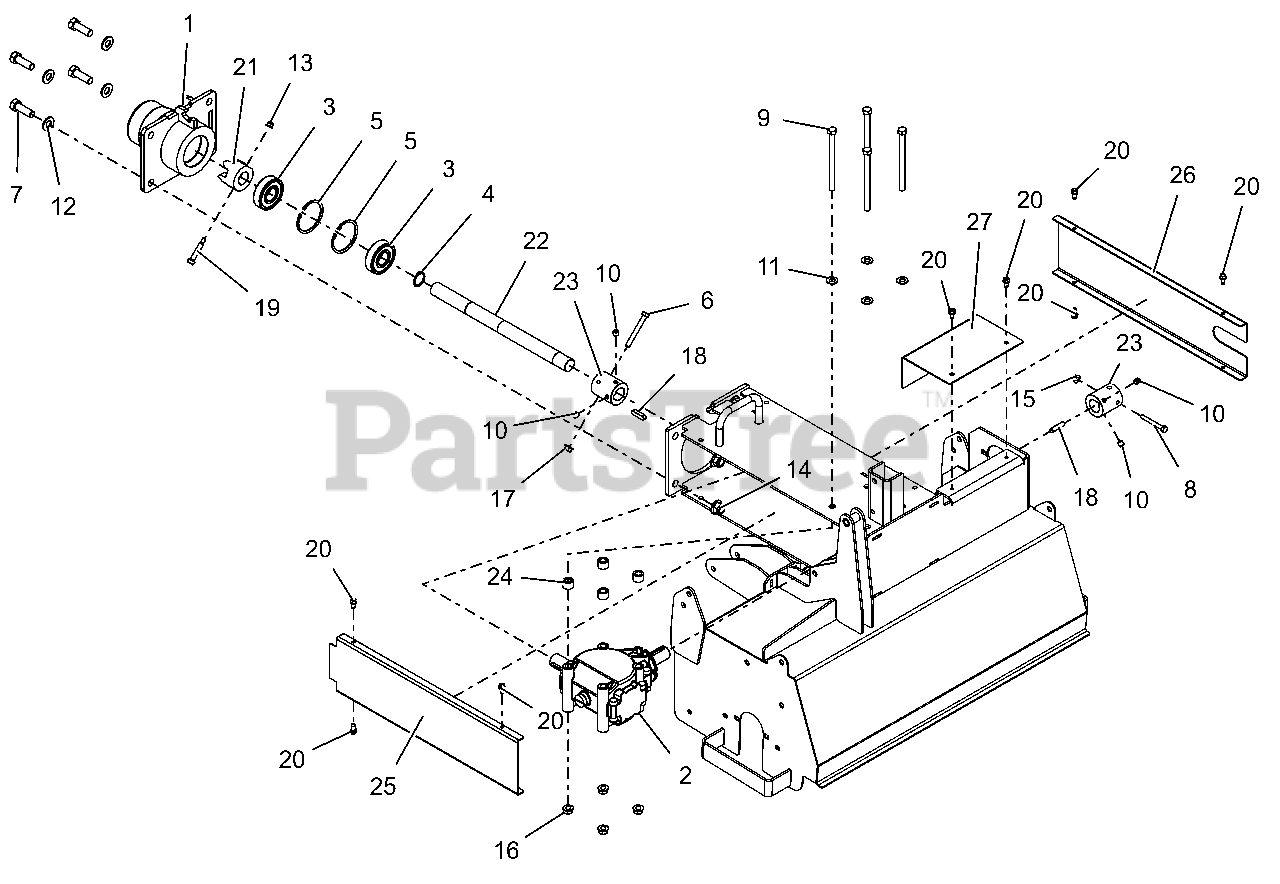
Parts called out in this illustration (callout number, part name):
1	WLDMT, CONNECTOR - RED
2	GEARBOX, 90 DEG- 1:1.9
3	BEARING, 6305LLC
4	RING, RETAINING-EXTERNAL 25MM X 1.2MM
5	RG-RTNG-INT 2.438X.078
6	BLT, HEX M8-1.25 X 65 G8.8 ZCC
7	BLT,HEX .50-13X1.50 G5 ZCC
8	BLT,HEX .25-20X2.25 G8 ZCC
9	BLT, HEX .38-16X5.00 G5 ZCC
10	SET SCREW, 3/8-24 X 3/8 (CUP)
11	WSHR,FLT .406X.812X.065 ZCC
12	WSHR,FLT .531X1.062X.095 ZCC
13	NUT,NYL-FLG M6-1.0 G8.8 ZCC
14	NUT,NYL-FLG .50-13 GF ZCC
15	NUT-LK-CTR-FLG .25-20 ZC120
16	NUT-LK-CTR-FLG .375-16 GF ZCC
17	NUT-LK-TOP-FLG M8 ZCC
18	KEY-STR 8X7X32MM ROUND ENDS
19	BLT,SHLDR M8X35
20	SCR-TAP .25-20X.50 HWH ZCC
21	ROUGH CUT CLAW COUPLING
22	SHAFT, INPUT
23	TUBE, CONNECTOR
24	SPCR, TUBE (BLACK)
25	SHIELD, RH
26	SHIELD, LH - BLACK
27	SHIELD, OUTPUT
